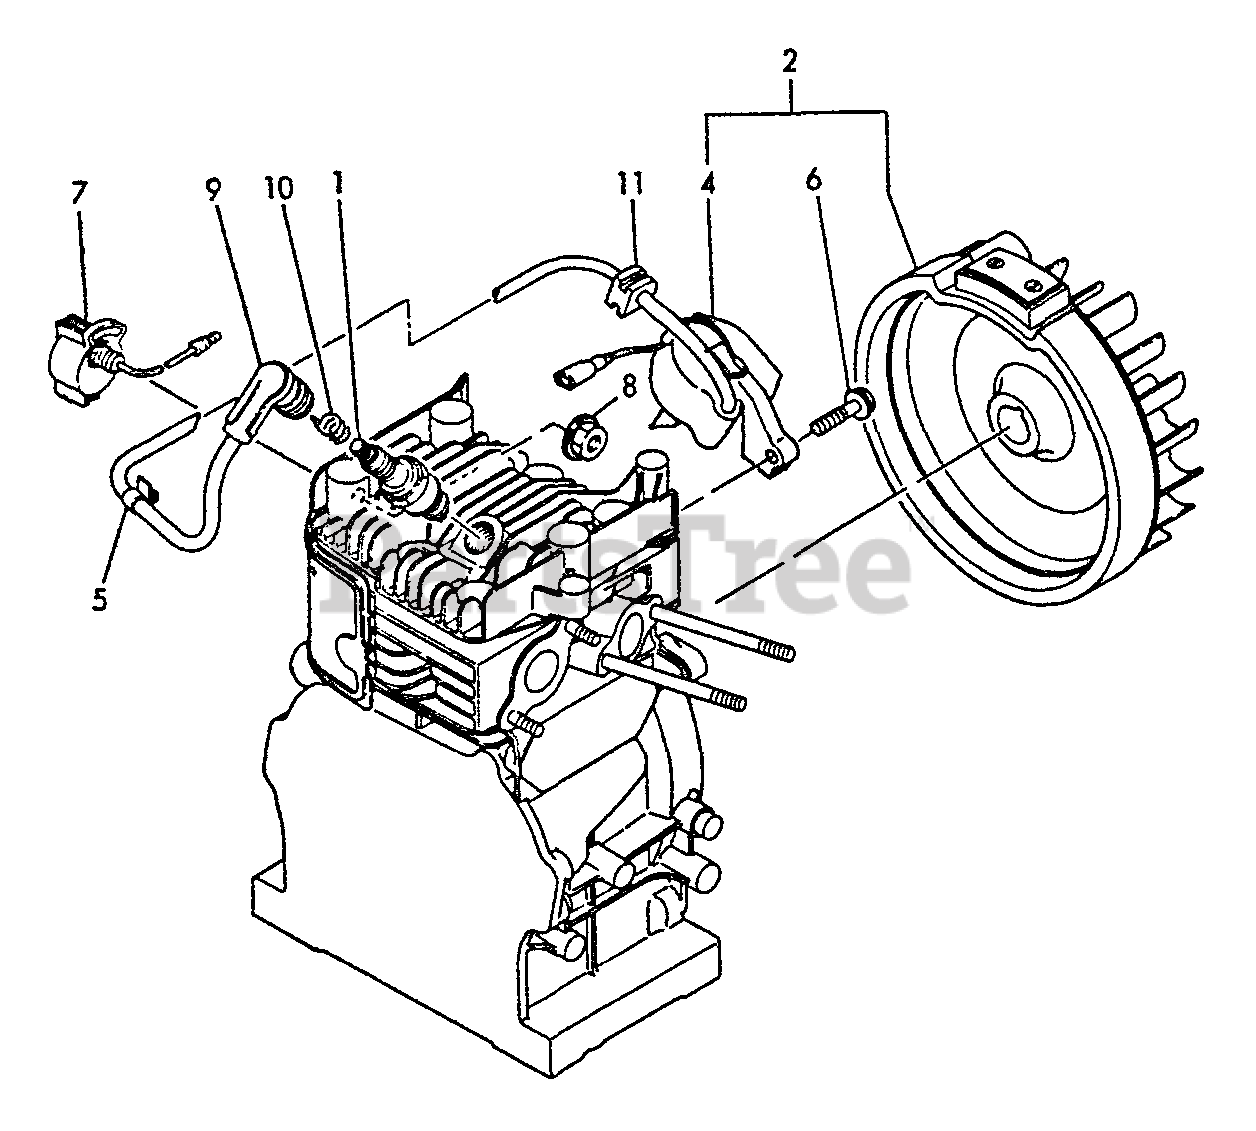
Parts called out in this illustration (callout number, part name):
1	SPARK PLUG
2	FLYWHEEL
4	COIL, IGNITION
5	CLAMP
6	BOLT - 6X25
7	IGNITION SWITCH ASSY
8	NUT - 8
9	CAP, PLUG
10	TERMINAL, SPARK PLUG CAP
11	GROMMET
